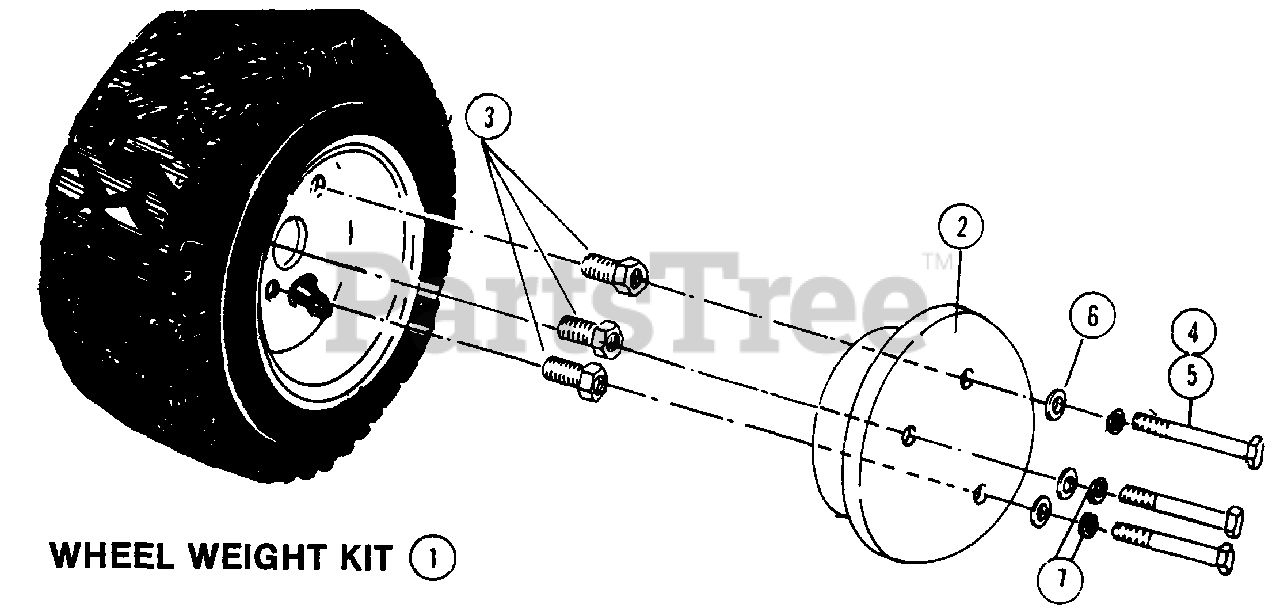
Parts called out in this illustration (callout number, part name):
1	KIT, Wheel Weight
2	WEIGHT, Wheel
3	STUD
4	CAPSCREW, 4-1/2 LONG
5	CAPSCREW, 3-1/4 LONG
6	WASHER, 3/8 SAE
7	LOCKWASHER, 3/8 SPLIT
